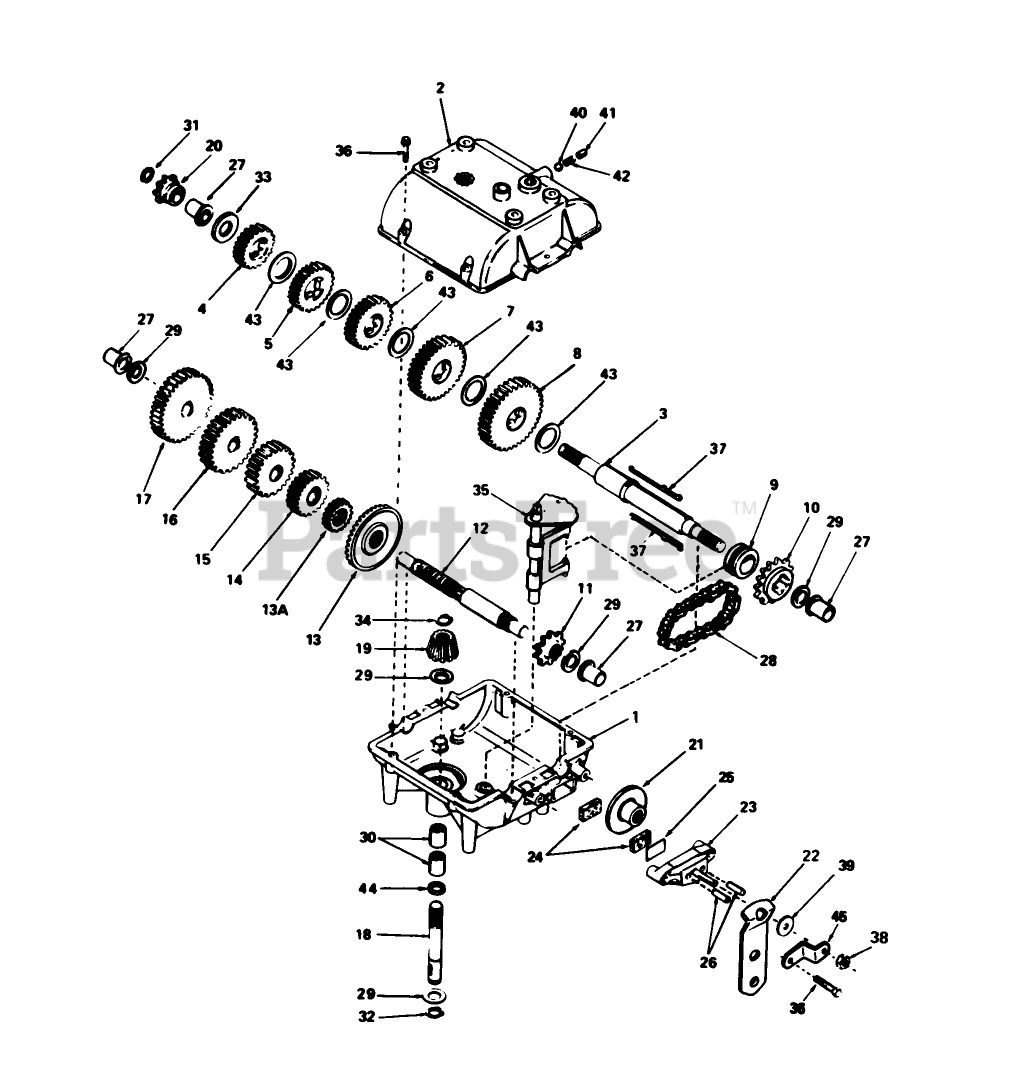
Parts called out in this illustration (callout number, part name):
1	Case-Transmission
2	Cover-Transmission
3	Shaft-Output Brake
4	Gear-Spur 20 teeth
5	Gear-Spur (22 teeth)
6	Gear-Spur, 25 Teeth
7	Gear-Spur, 30 Teeth
8	Gear-Spur, 35 Teeth
9	Collar-Shift
10	Sprocket-18 Teeth
11	Sprocket-9 Teeth
12	Countershaft
13	Gear-Bevel (42Teeth)
13A	Gear-Spur 15 Teeth
14	Gear-Spur, 20 Teeth
15	Gear-Spur, 25 Teeth
16	Gear-Spur (28 teeth)
17	Gear-Spur (30 teeth)
18	Shaft-Input
19	Bevel Pinion-Input
20	Sprocket (8 teeth)
22	Lever-Brake
23	Nozzle-Carburetor
24	Brake Pad
25	Brake Pad Plate
26	Dowel Pin
27	Bushing-Flange
28	Chain-Roller #41
29	Washer
30	Bearing-Needle
31	Piston Asm (.020 O S)
32	Ring-Snap
33	Washer
34	Ring-Retainer
35	Rod and Fork ASM
36	Ring Set (.020 O S)
38	Locknut
39	Washer
40	Ball-Steel
41	Screw-Set
42	Spring
43	Washer
44	O Ring
45	Bracket
